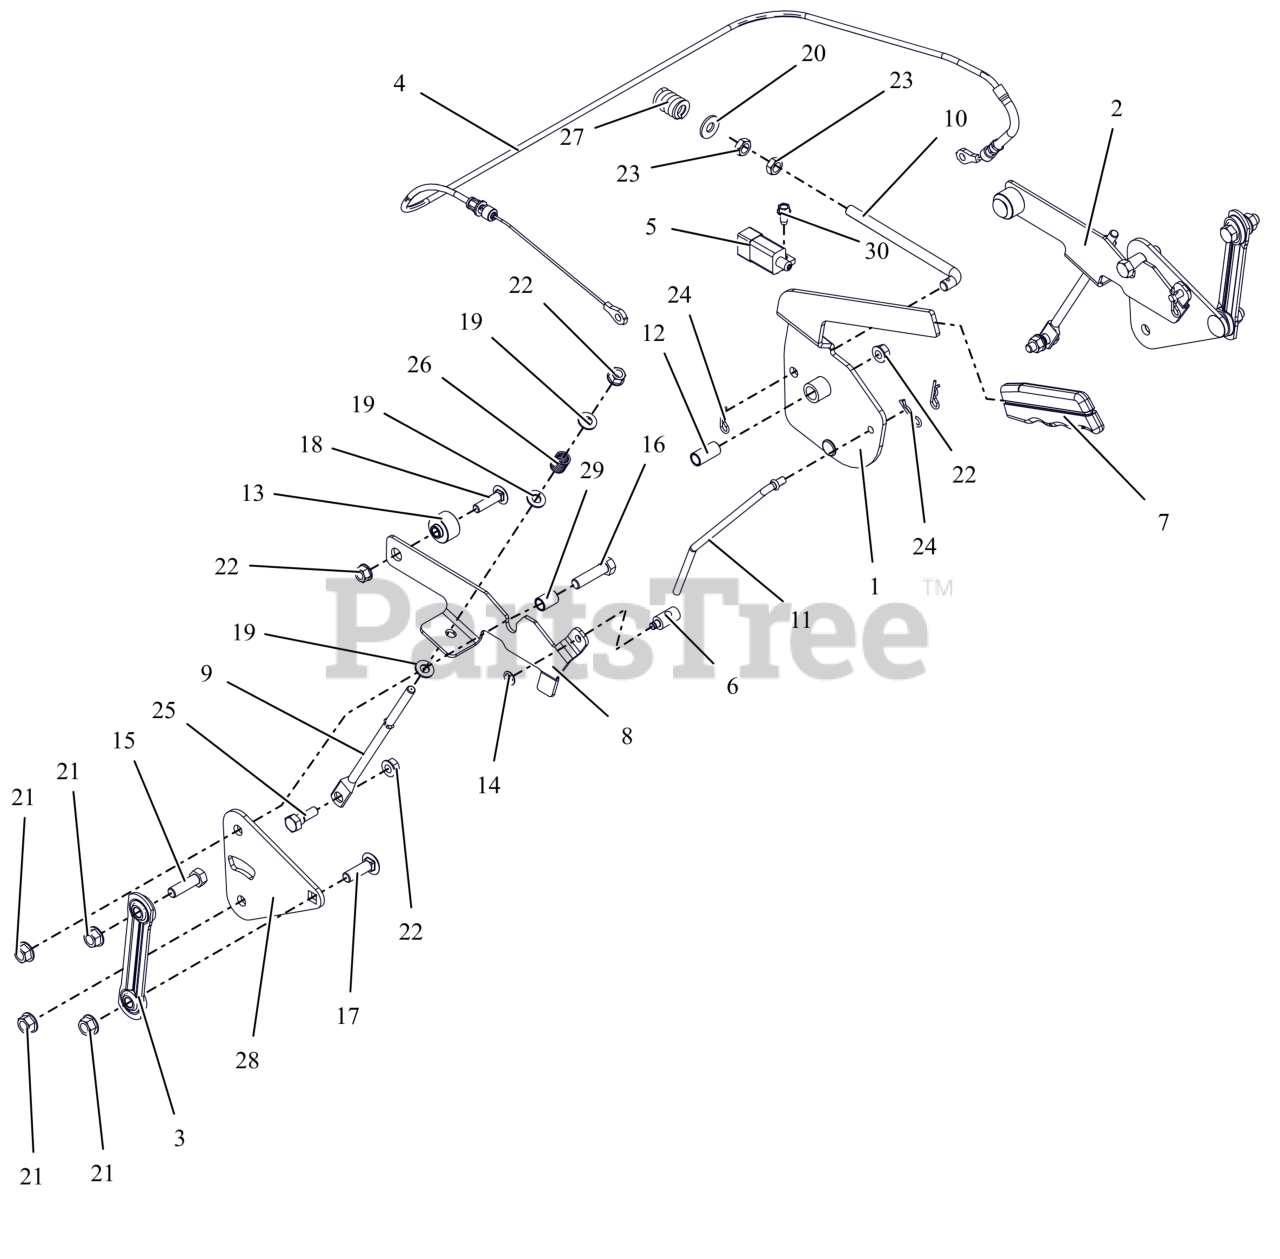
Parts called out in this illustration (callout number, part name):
1	LEVER, PARKING BRAKE
2	ARM, BRAKE - LH (W/PIN)
3	LINK, STAMPED STEERING
4	CABLE, BRAKE - PARKING
5	SWITCH-BRAKE NO/NO-POST & HOLE
6	TRUNION, 1/4-20
7	GRIP, PARKING BRAKE (GREY)
8	ARM, BRAKE - RH
9	ROD, LINK - TRANSMISSION BRAKE
10	ROD, OVER CENTER
11	ROD, BRAKE LINK
12	BSHG-SLV .385X.500X1.045
13	SPCR, FLANGE
14	RG-RTNG-EXT .250X.025
15	BLT, HEX .38-16X1.25 G5 ZCC
16	BLT, HEX .38-16X1.50 G5 ZCC
17	BLT,RHSSN .38-16X1.25 G5 ZCC
18	BLT, RHSSN.31-18X1.25 G5 ZCC
19	WSHR,FLT .344X.688X.065 ZCC
20	WSHR,FLT .375X.875X.083 ZCC
21	NUT-LK-TOP-FLG .38-16 ZC120
22	NUT-LK-TOP-FLG .312-18 GF ZCC
23	NUT-JAM .375-16 G2 ZCC
24	PIN, HAIR #213 .08X1.19 ZCC
25	BOLT,SHLDR .38X.25 -.31-18X.75
26	SPRING, COMPRESSION
27	SG-COMP .187X.56X1.62
28	PLATE, TRANSAXLE (BLACK)
29	SPCR SLEEVED .385X.500X.718
30	SCR-TAP .25-20X.50 HWH ZCC
